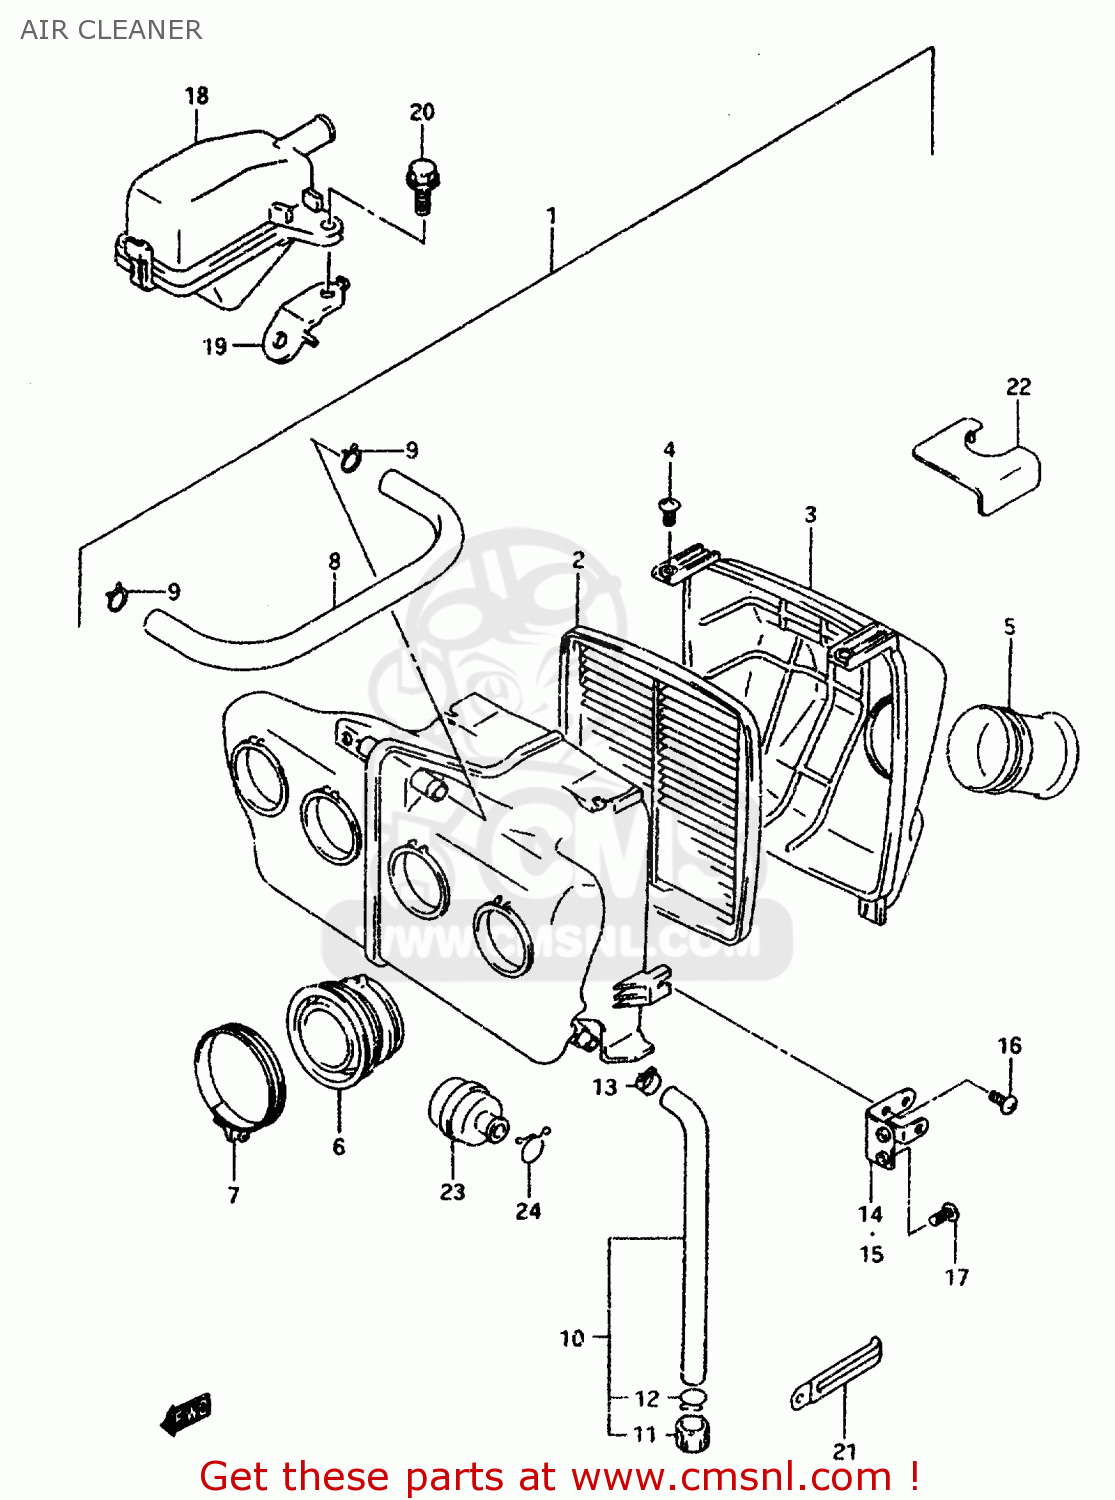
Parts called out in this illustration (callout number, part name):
1	CLEANER ASSY,AIR
2	FILTER,AIR
3	CAP,AIR CLEANER
4	SCREW 5X12
5	TUBE,INLET
6	TUBE,OUTLET
7	CLAMP
8	TUBE,BREATHER
9	CLIP
10	TUBE,DRAIN
11	CLIP
12	STOPPER,DRAIN
13	CLIP
14	BRACKET COMP,AIR CLEANER
15	BRACKET COMP,AIR CLEANER
16	SCREW 6X12
17	SCREW
18	CLEANER ASSY,AIR NO.2
19	BRACKET,AIR CLEANER NO.2
20	BOLT
21	CLAMP
22	COVER,AIR CLEANER
23	FILTER,AIR CLEANER NO,2
24	CLIP
